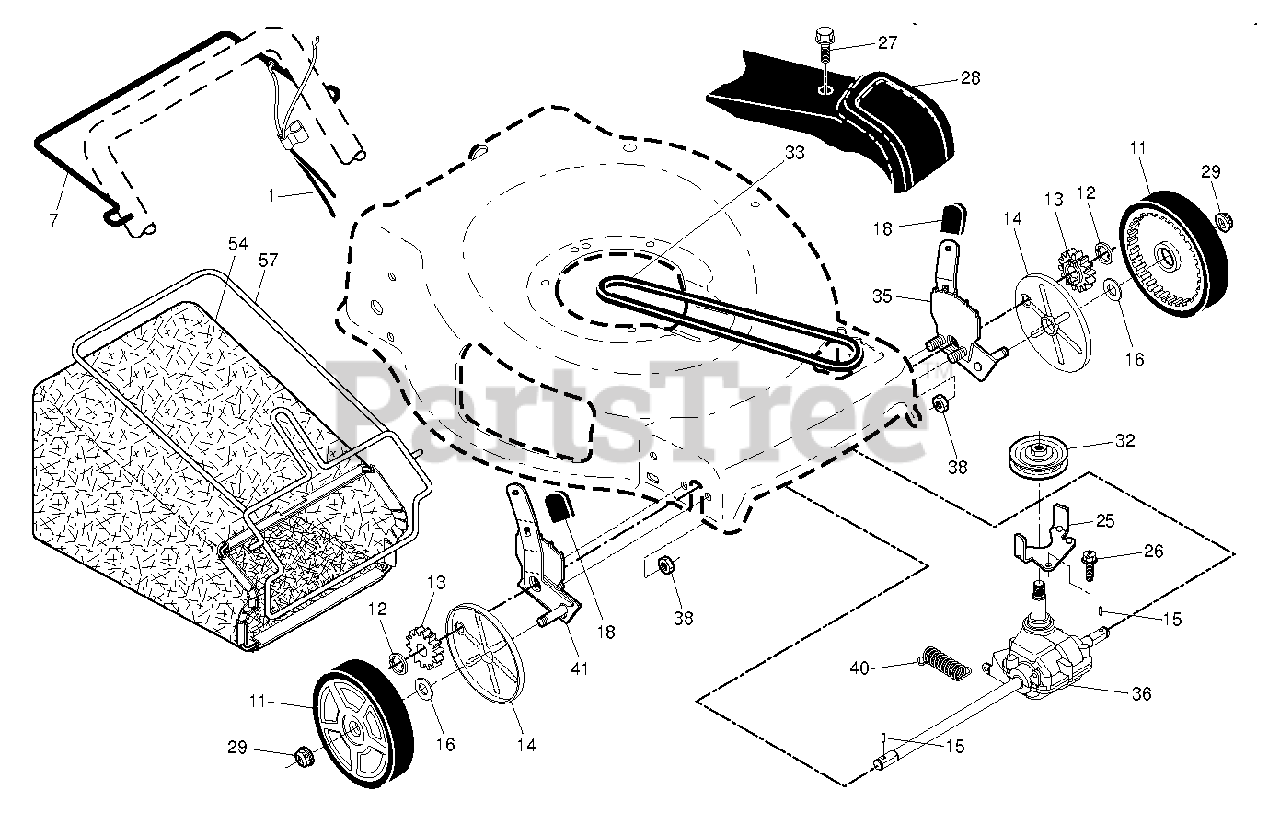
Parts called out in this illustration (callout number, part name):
1	CABLE.DRIVE.S/S.22+.FWGD
7	BAIL.DRIVE.S/S.ROUND.MARI.21
11	WHEEL.8X1.75.5SPK.RAD3.BLACK
12	E-RING 7/16 RE
13	PINION.14.TEETH.FGD
14	COVER.DUST.WHEEL.INNER.WALK
15	PAWL, DRIVE
16	WASHER FLUT
25	BRACKET.BELT.GUIDE.22+FGD.BZP
27	SCREW, HEX HD TAPPING #10-24 1
28	COVER.DRIVE.22+.MB.GEN.FGD
29	NUT.HEX.FLANGE.3/8-16.LOCKNUT
32	PULLEY.DRIVE.EZ/VARI.SCREWON
33	BELT.DRIVE.FGD.
35	ADJUSTER.ASM.9.22+/RF/LR.21/RF
36	TRANSMISSION.22+.FWGD.SS
38	NUT.HEX.FLANGE.1/4
41	ADJUSTER.ASM.9.22+/RF/LR.21/LF
54	GBAG.A1640416S.BLK.PPRO.MRG.
57	Grass Bag Frame, 22+ Black
